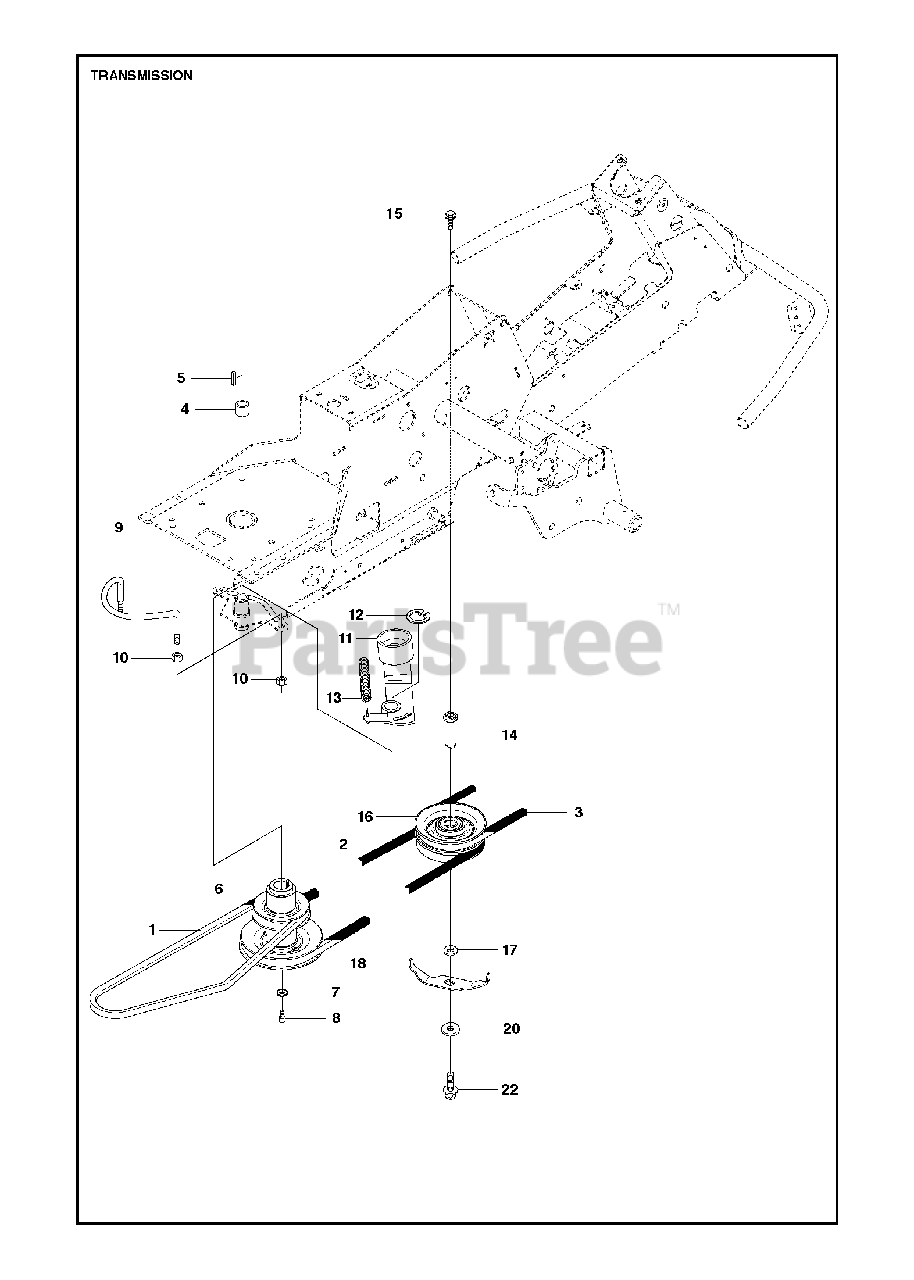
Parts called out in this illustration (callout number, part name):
1	BELT
2	BELT
9	BELT GUIDE
11	TENSIONER
12	RETAINING RING SGA 25
14	SHAFT
18	BELT GUIDE
22	BOLT
25	PULLEY
26	BUSHING
